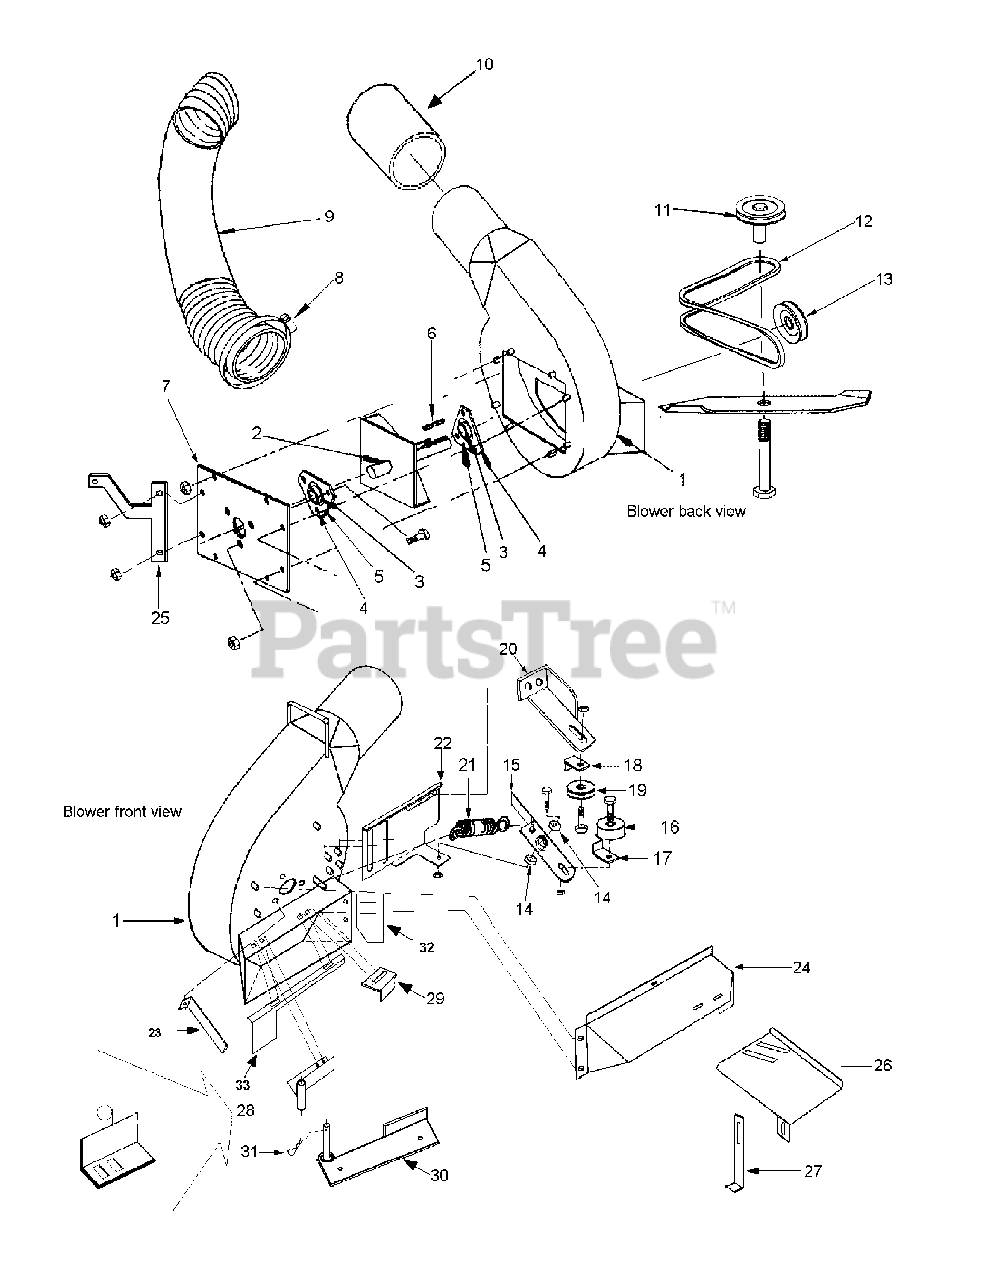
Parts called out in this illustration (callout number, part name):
1	Blower Canister
3	Fan Bearing w/ collar
4	Bearing Flangette w/ grease zerk
5	Bearing Flangette
6	Key 1/4" x 1"
7	Blower Cover Plate
8	6" Hose Clamp
9	6" x 43" Hose
10	6" Hose Insert
11	Deck Pulley
13	Blower Drive Pulley 3.5"
14	Idler Arm Bearing
15	Idler Arm
16	Flat Idler Pulley 3.25"
17	Flat Idler Pulley Bracket
18	V-Idler Pulley Bracket
19	V-Idler Pulley 3.5"
20	V Pulley Bracket
21	Idler Spring
22	Blower Pulley Bracket
23	Fan Pulley Belt Bracket
24	Blower Belt Cover
25	Pulley Bracket Support
26	Belt Guard Leg
27	Belt Guard Leg
28	Blower Mount Front
29	Blower Support Bracket
30	Blower Mount Deck
32	Blower Tab
33	Blower Blocking Plate
